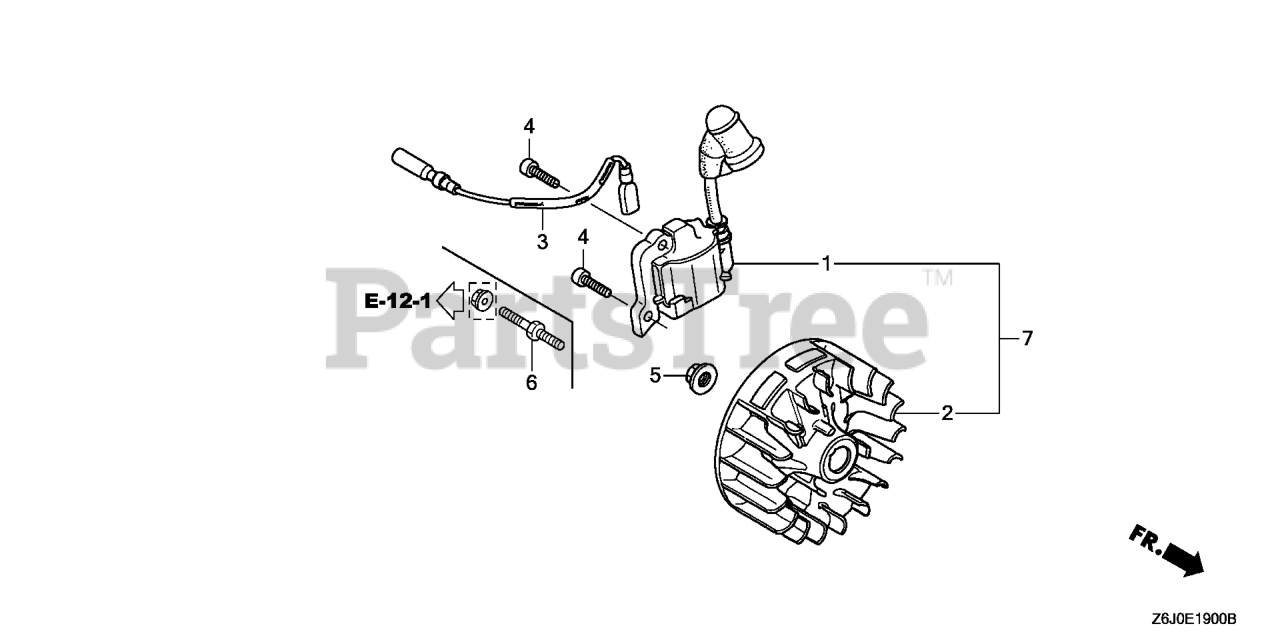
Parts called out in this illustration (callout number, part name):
1	COIL ASSY., IGNITION
3	WIRE, STOP SWITCH
4	BOLT, SOCKET (4X14)
5	NUT, FLANGE (7MM)
